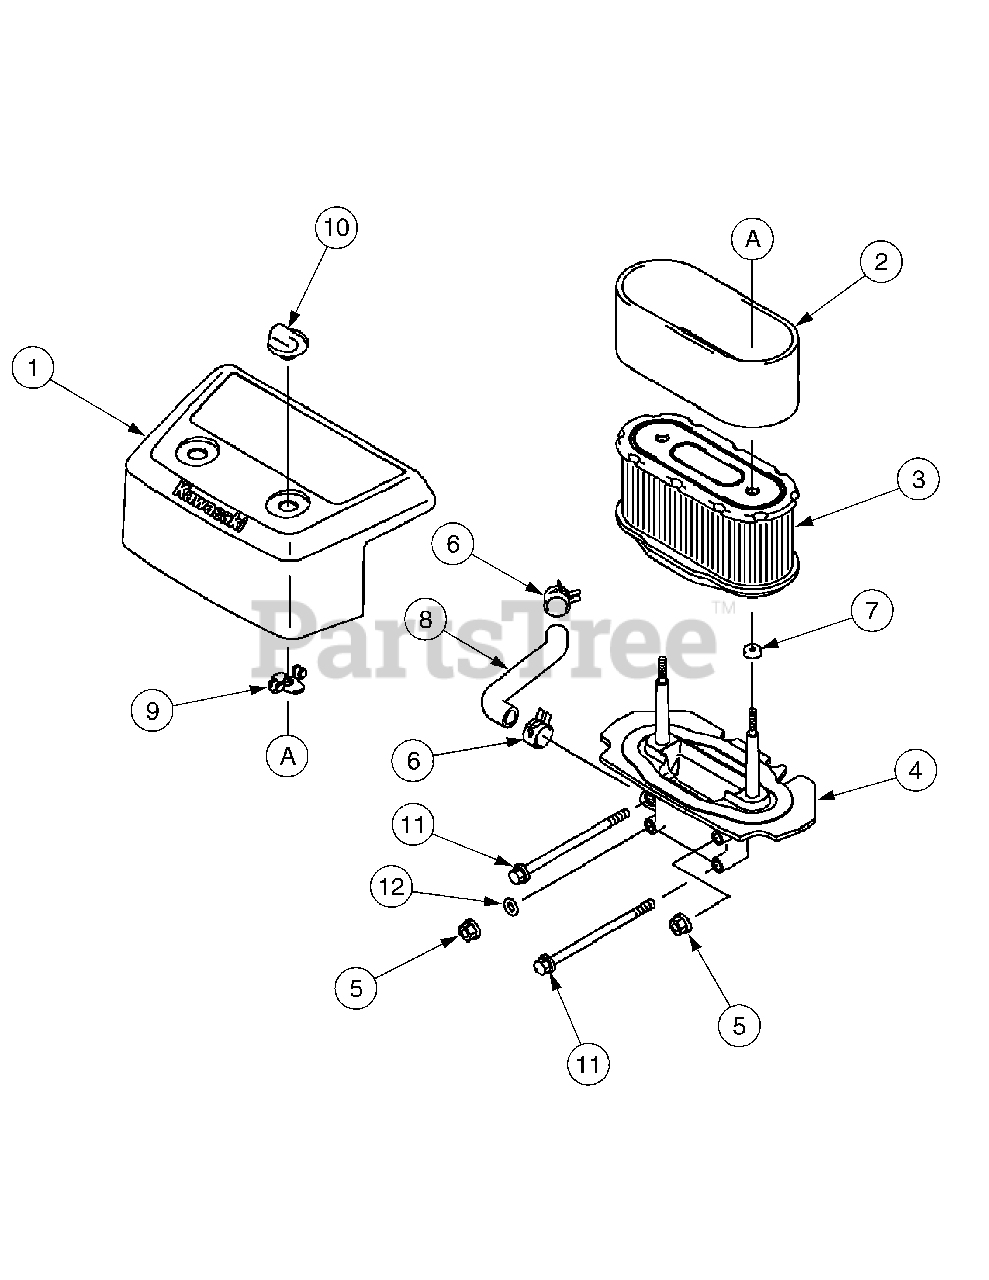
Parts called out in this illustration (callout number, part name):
1	Air Filter Case with 2 nuts
2	Element, Air Filter
3	Element, Air Filter
4	Pipe, Intake
5	Nut
6	Clamp
10	Nut NLA
11	Bolt, Flanged
12	Washer, Plain
